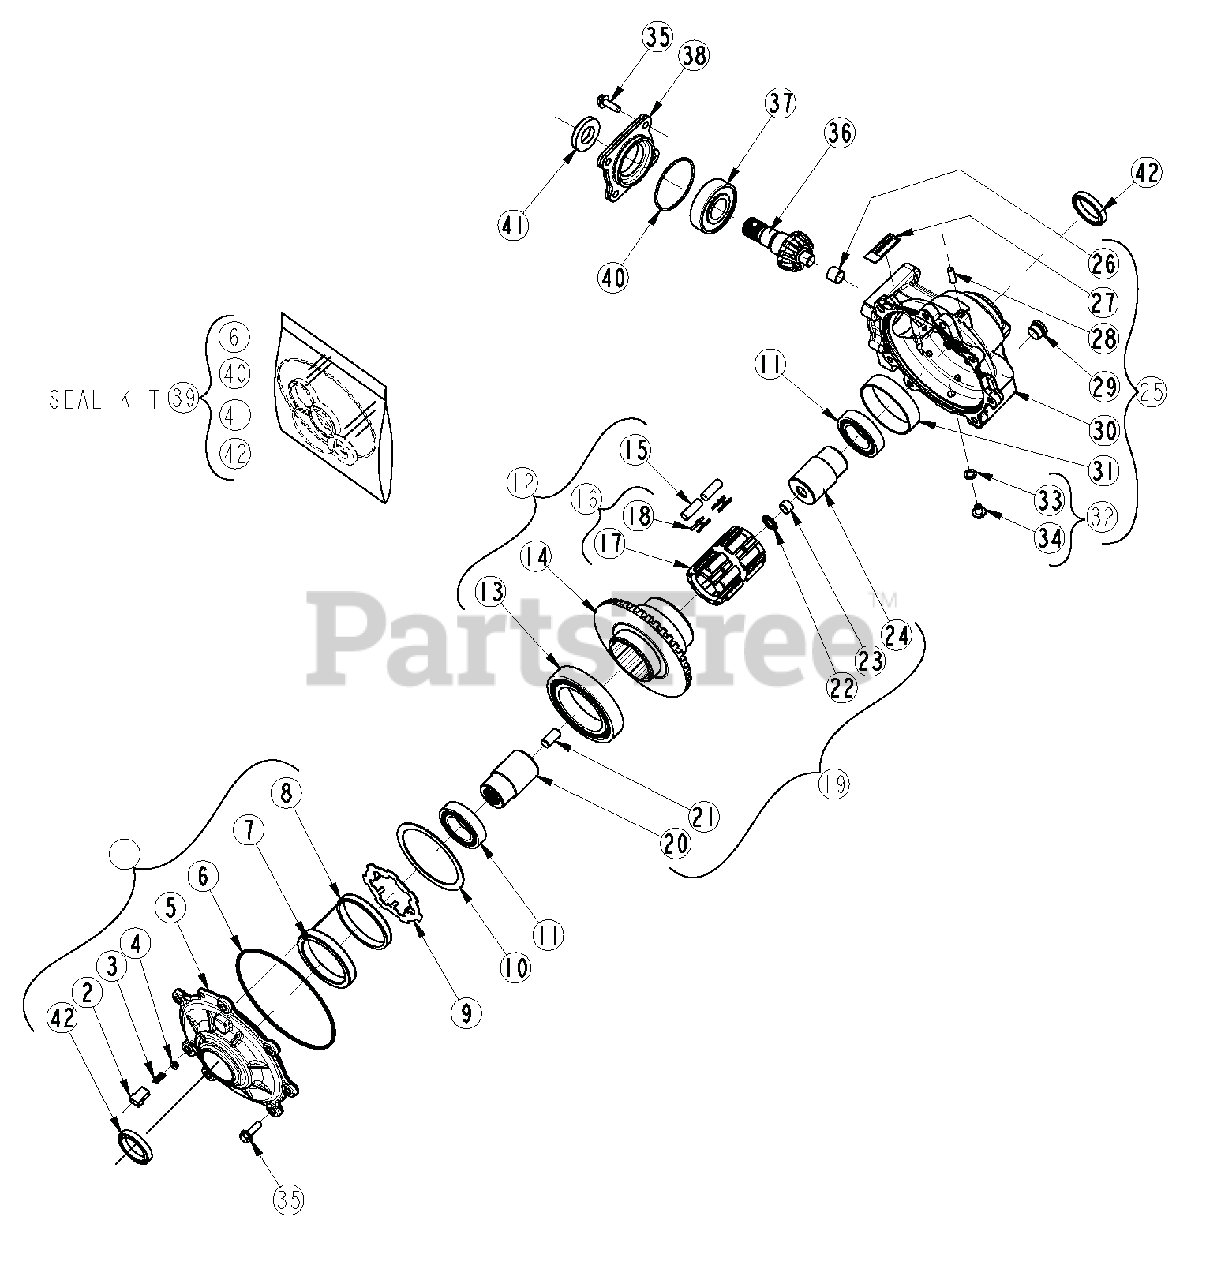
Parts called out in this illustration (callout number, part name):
1	OUTPUT COVER PLATE ASSEMBLY
2	MATE-N-LOK - HOUSING (Sold with #1 Kit)
3	MATE-N-LOK PIN (Sold with #1 Kit)
4	GROMMET, OUTPUT COVER (Sold with #1 Kit)
5	COVER PLATE, OUTPUT - MACHINED (Sold with #1 Kit)
6	O-RING, OUTPUT - 164S (SQ. RING) (Sold with #1 Kit & #39 Kit)
7	COIL POCKET INSERT (Sold with #1 Kit)
8	COIL WITH PRESS FIT BOBBIN (Sold with #1 Kit)
9	ARMATURE PLATE
10	SHIM, ARMATURE PLATE
11	6008-C3DEP.GRVE.ROLLER BEARING
12	CLUTCH ASSEMBLY
13	6015-C3 DP.GRV RLLR BAL BEARNG
14	CLTCH.HSG./RNG GR.,42T 6.75DP
15	ROLL KIT
16	ROLL CAGE ASSEMBLY
17	ROLL CAGE, PLASTIC-MACHINED (Sold separately & with #16 Kit)
18	SPRING KIT,H-CLIP .008 THK
19	RACE/OUTPUT HUB ASSEMBLY
20	RACE/OUTPUT HUB, FEMALE (Sold with #19 Kit)
21	PERMIGLIDE BUSHING (Sold with #19 Kit)
22	TC815 NDLE.RLLER.THRST BEARING
23	1/2 DIA X 1 LG. DOWEL PIN
24	RACE/OUTPUT HUB, MALE (Sold with #19 Kit)
25	GEARCASE ASSEMBLY
26	DU BUSHING (Sold with #25 Kit)
27	LABEL, BAR CODE (Sold with #25 Kit)
28	TUBE, VENT 1/2 HOSE (Sold with #25 Kit)
29	PLUG OIL FILL 3/4-16 HOLLOW HD
30	GEARCASE, LEFT HAND - MACHINED (Sold with #25 Kit)
31	BUSHNG, SELF LUBRICATING 80 X 85 X 20 (Sold with #25 Kit)
32	DRAIN PLUG ASSEMBLY
33	WASHER, .625 X .06, NYLON 6/6 (Sold with #32 Kit)
34	PLUG, OIL DRAIN, 3/8-16HH FLANGE WITH MAG. TIP (Sold with #32 Kit) Torque Item 34 (PLG, OIL DRAIN, 3/8-16HH FLNGE W/M) Tighten to 9 ft-lbs.
35	BOLT KIT
36	PINION SHAFT HILLIARD
37	6306-03-C3 DP GRV RLLR BL BRG
38	COVER PLATE,INPUT-MACHINED
39	MINOR REPAIR KIT
40	0-RING, INPUT, 148S (Sold with #39 Kit)
41	TRIPLE LIP OIL SEAL (Sold with #1 Kit & #39 Kit)
42	OIL SEAL, OUTPUT (Sold with #39 Kit)
43	KIT - GEAR, HARD TURNED
